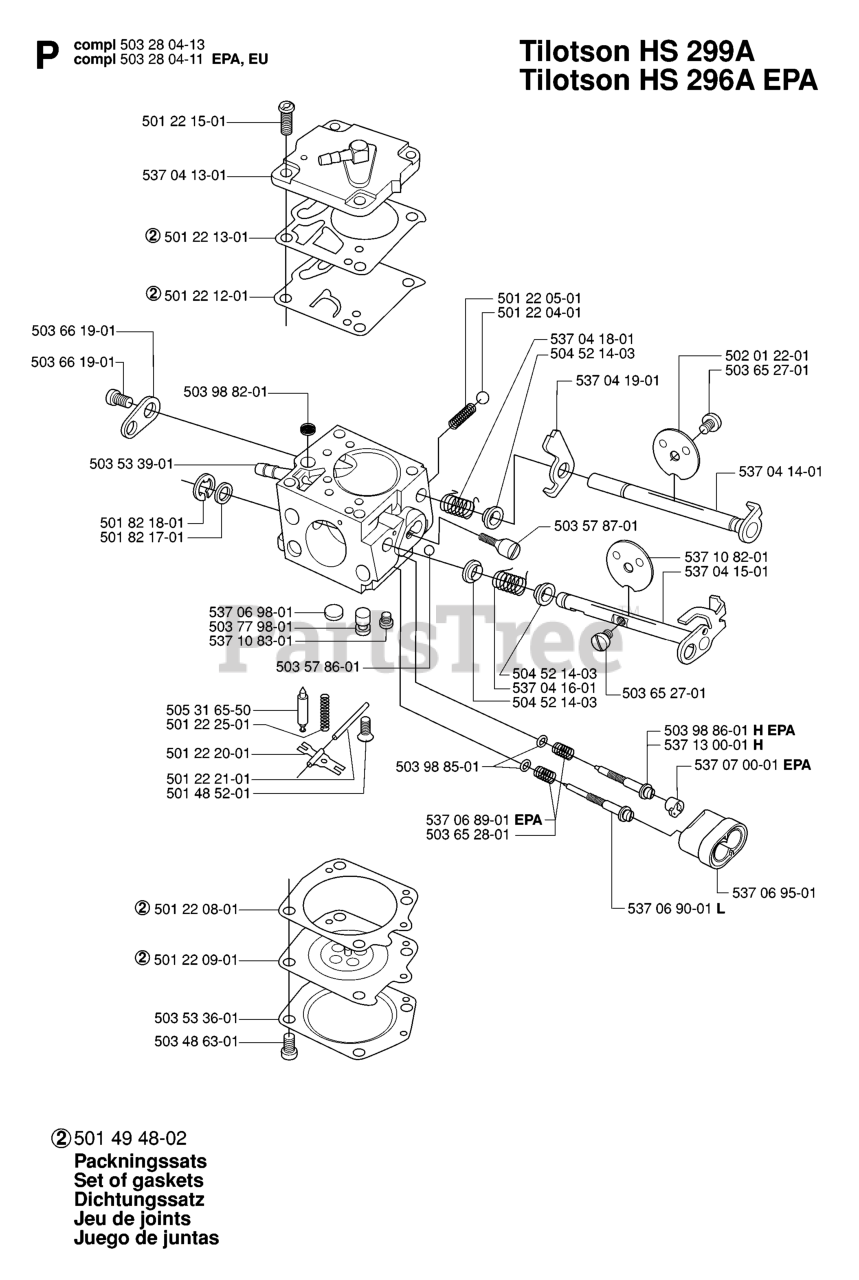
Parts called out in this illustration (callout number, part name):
2	RP BOLT 5/16-18 X3/4 ZN/YEL GR
3	BRKT ASM SWAY BAR
5	RETAINER-SPRNG RB
6	BAR SWAY DECK
8	BLADE BOLT
9	LOCKWASHER
10	WASHER.BLADE
11	BLADE, HI-LIFT 36" PREMIUM
13	SHAFT ASM VENT
14	HOUSING.MANDREL.VENTED (MACHD)
16	STRIPPER.MANDREL.ROUND.BLACK
19	BOLT SHD 5/16-18
21	LOCKNUT
23	BRACKET ASM DEFLECTOR
24	CAP-SLEEVE LT
25	SPRING TORSION
26	NUT PUSH M
27	CONSOLE.STLT.5SP.BLK
28	Washer 11/32 x 5/8 x 16 Ga SD
29	HINGE ROD
30	SCREW, WASHER HEAD
31	WASHER
32	PULLEY, MANDREL
33	NUT, FLG TOPLOCK 9/16"
36	FLAT IDLER PULLEY
45	RETAINER M
53	BRAKE ASSEMBLY
54	HARDENED WASHER
56	SPACER.RETAINER.MOWER
67	KNOB T (3/8 HOLE)
68	V-BELT.MOWER.
89	WASHER GT
92	NUT
107	SPACER.IDLER.ARM
108	STIFFENER.IDLER.ARM
113	Screw 5/16-18 x 1/2 Hex, Self Tapping 5/16-18 x 1/2
129	WASHER
131	BOLT D
146	BOLT, CARRIAGE IDLER
148	IDLER RETURN SPRING
149	SPRING.RETAINER.YELLOW.ZINC
151	BRACKET.CLUTCH.CABLE
153	WASHER FLAT 3/8"
154	SPRING RETAINER
155	SPRING RETENTION LEVER
156	SPACER.CLUTCH.CABLE
157	ROD CLUTCH CABLE 3/8"
158	SCREW
171	BRACE.SUPT.SUSP.FRT.CRD
